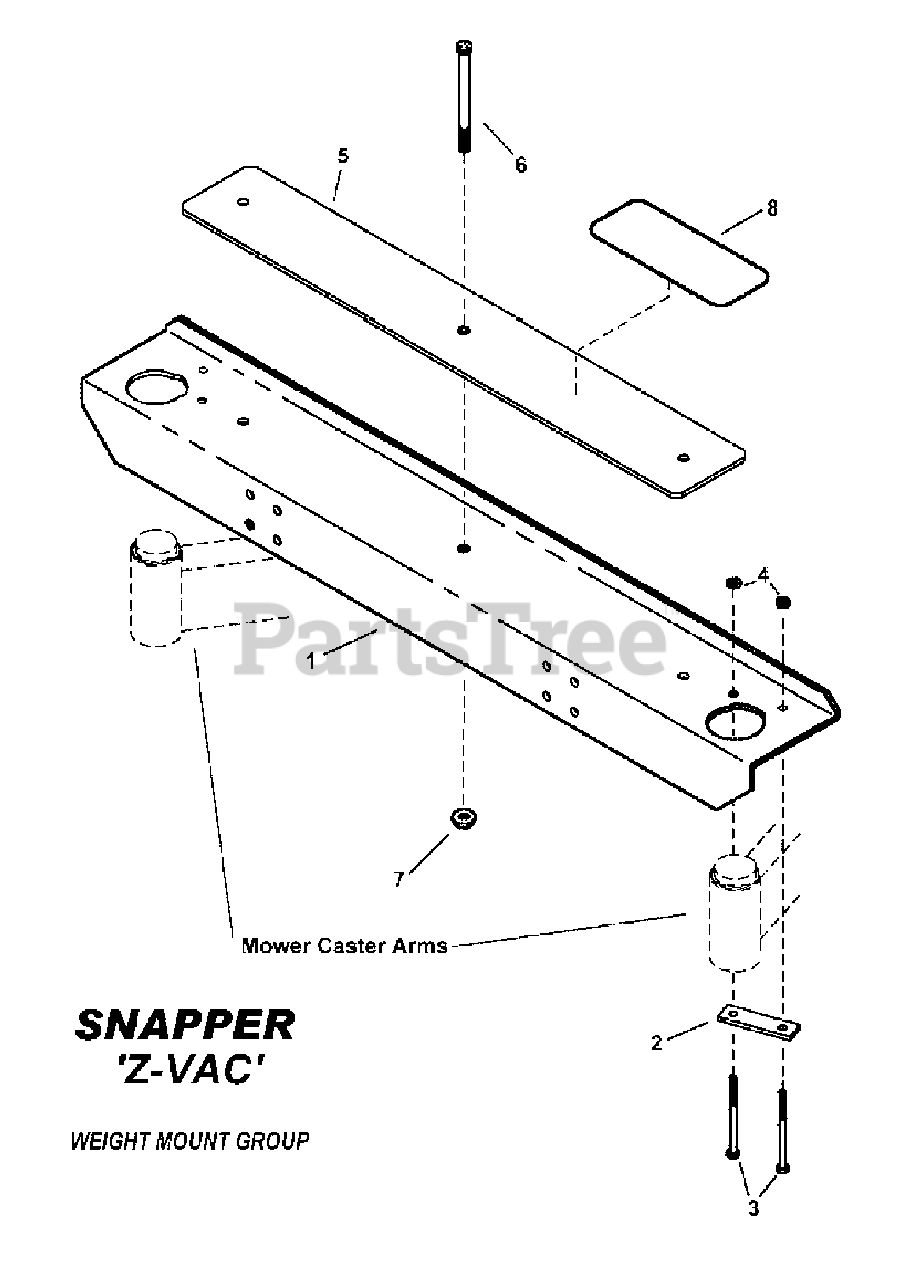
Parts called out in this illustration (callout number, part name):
1	CHANNEL, Weight Mounting
2	CLAMP, Bar
3	BOLT, 3/8CX4
4	NUT, Hex Cap Lock 3/8-16
5	WEIGHT, NZM
6	SCREW, Hex Head Cap 1/2-13 X 5.50 GR 5 YZ
7	NUT, Flange Lock, 1/2C
8	PAD, Anti-Skid
